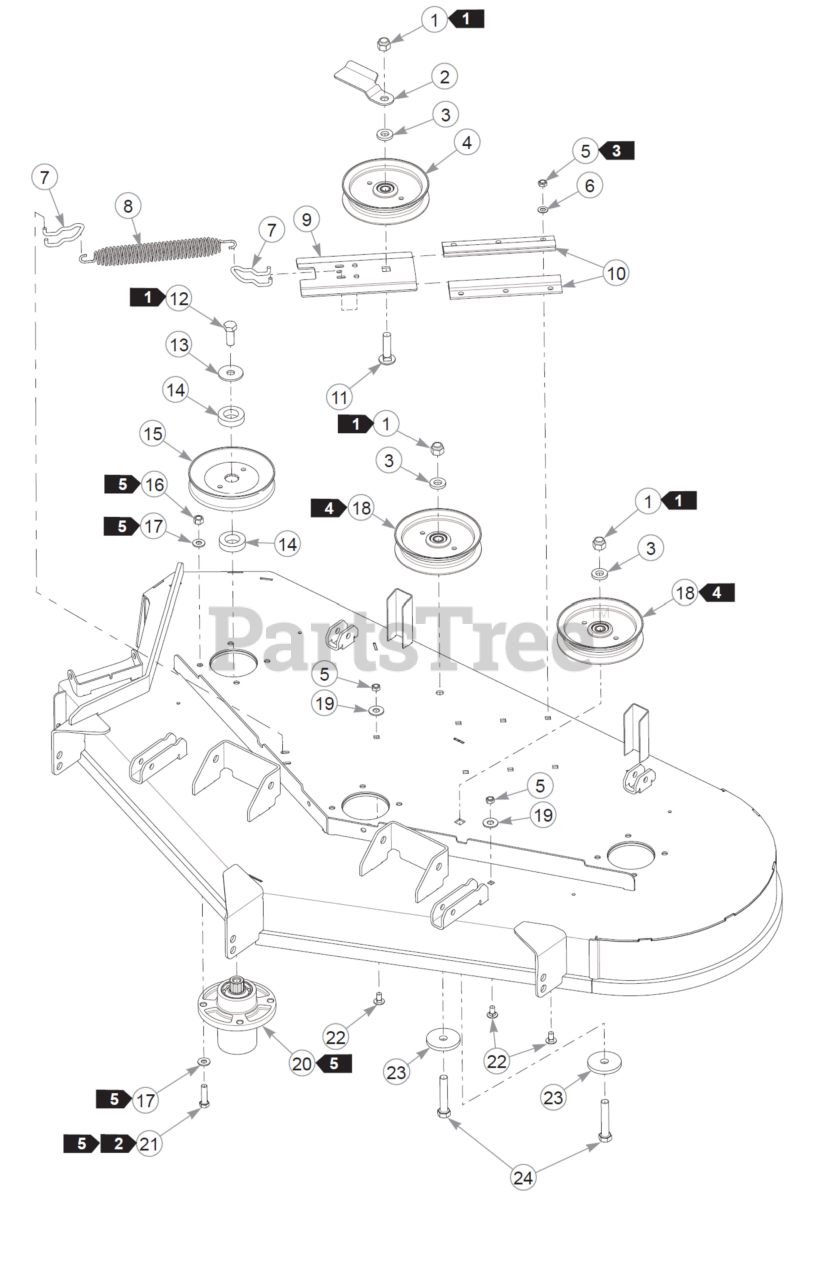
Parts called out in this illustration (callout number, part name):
1	NT .500-13NLG5
2	BELT GUIDE
3	FW .531 x 1.063 x .175
4	IDLER PULLEY, 5.00"
5	NT .312-18 HXNL JAM G2ZN
7	ANCHOR, SPRING TENSIONER
8	SPRING, DECK IDLER
9	SLED, IDLER
10	IDLER SLIDE, EXTRUDED
11	CB .50-13 X 2.00 STD ZN
12	CS .500-13X1.25 HX G5 ZN
13	FW .515X1.65X.12 HD ZN
14	SPACER, SPINDLE PULLEY
15	PULLEY, DECK DRIVE B-SEC
16	NT .375-16HXG5
17	FW 0.379X.82X.06 HD ZN
18	SVC KIT 604231 PULLEY
19	FW .440X1.00X0.08 ZN
20	BLADE SPINDLE ASSY
21	CS .375-16X1.38 HX G5 ZN
22	CB .312-18X .620 G5 ZN
23	FW .531 x 2.25 x .25 ZN
24	CS .500-13X2.750HXG5
